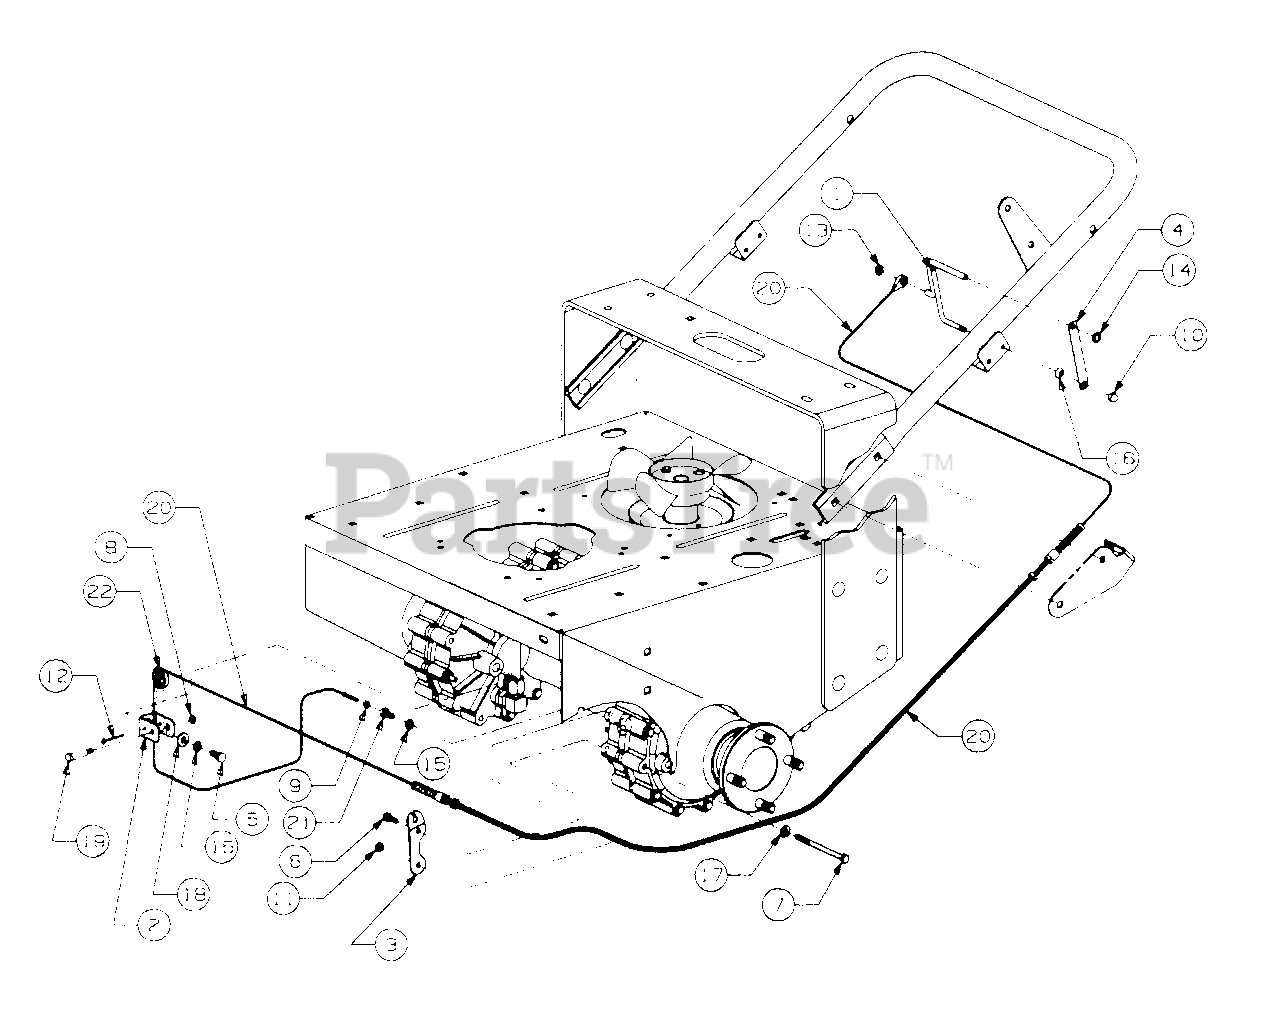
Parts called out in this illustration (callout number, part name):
1	Lever, Drive Wheel Release
2	Bracket, Pulley Mtg
3	Plate, Release Cable Mtg
4	Plate, Retainer
5	Screw, Hex, Cap, 5/16-24 X .75 Lg GR5
6	Screw, Hex Wash Hd Tapp, 1/4-20 X 4.0 Lg
7	Screw, HexCap, 1/4-20 X 4.0Lg
8	Nut, Hex Top Lock, 1/4-20
9	Nut, Hex, #10-32
10	Nut, Hex Lock Stop, 1/4-28
11	Nut, Hex Top Lock, 1/4-20 GR5
12	Pin, Cotter, 5/32 Dia X 1.25 Lg
13	Nut, Cap Speed, .312 Stud
14	Nut, Push-On Speed, 5/16
15	Washer, Lock, 5/16
16	Washer, Spring
17	Washer, Flat, .25 X .62
18	Washer, Flat, .312 X .750 X .119 Thk
19	Bolt, Pulley
20	Cable, Drive Wheel Release
21	Bolt, Cable Adapter
22	Pulley, Cable
